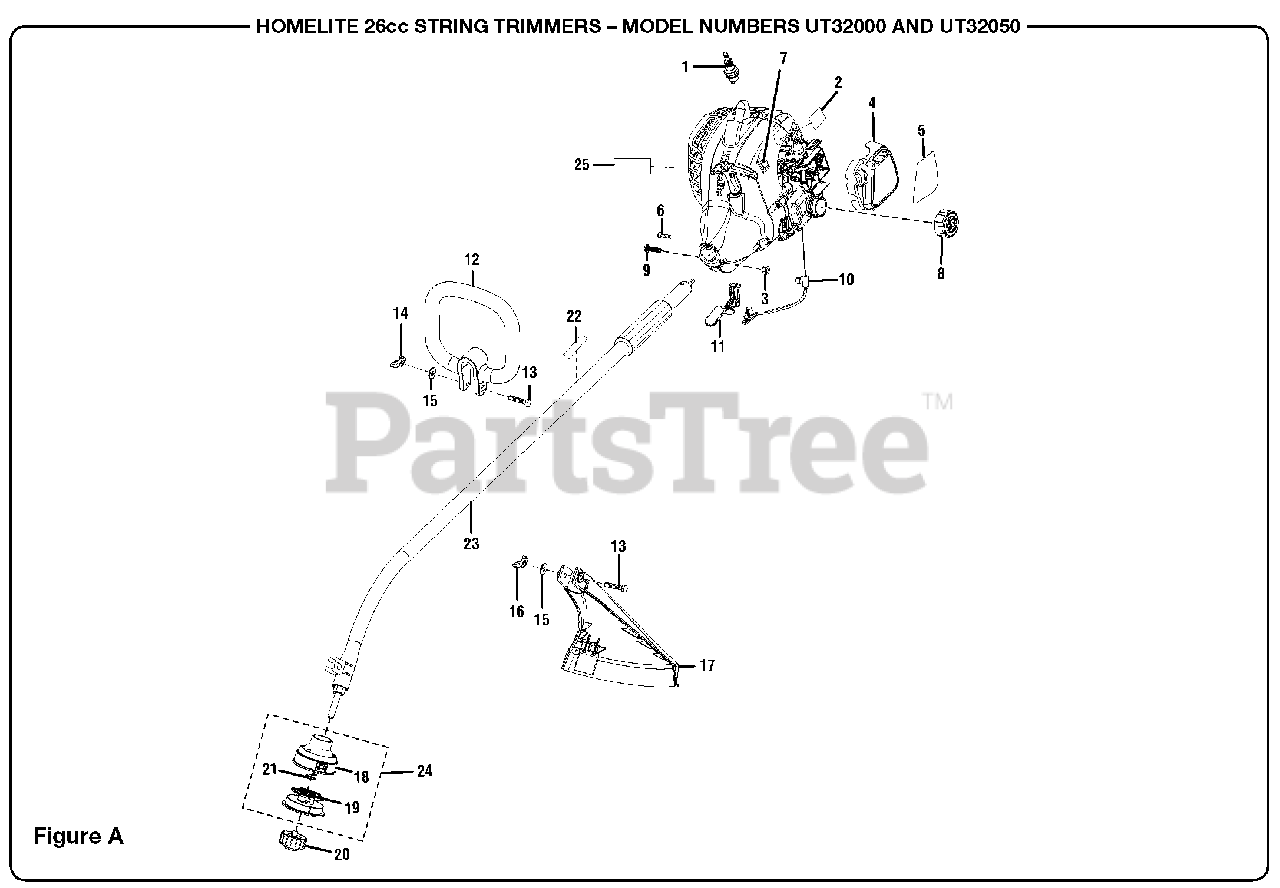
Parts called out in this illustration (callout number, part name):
1	Spark Plug (Champion RCJ6Y)
2	Logo Label
3	Hex Nut (M6)
4	Air Box Cover
5	Starting Label
6	Screw (8-16 x 5/16 in.)
7	Switch
9	Bolt (M6 x 20 mm)
10	Throttle Cable
11	Throttle Trigger
13	Bolt (1/4-20 x 45 mm)
14	Wing Nut (1/4-20)
15	Washer (1/4-20)
16	Wing Nut (1/4-20)
17	Curved Shaft Grass Deflector (Incl. Key Nos. 13 and 15-16)
18	Dual String Head Housing
19	Dual Line Spool and String (0.080 in.)
20	Spool Retainer
21	Spring
22	Warning Label
23	Boom Assembly
24	String Head Assembly (Incl. Key Nos. 18-19 and 21)
25	Combusion Warning Label
